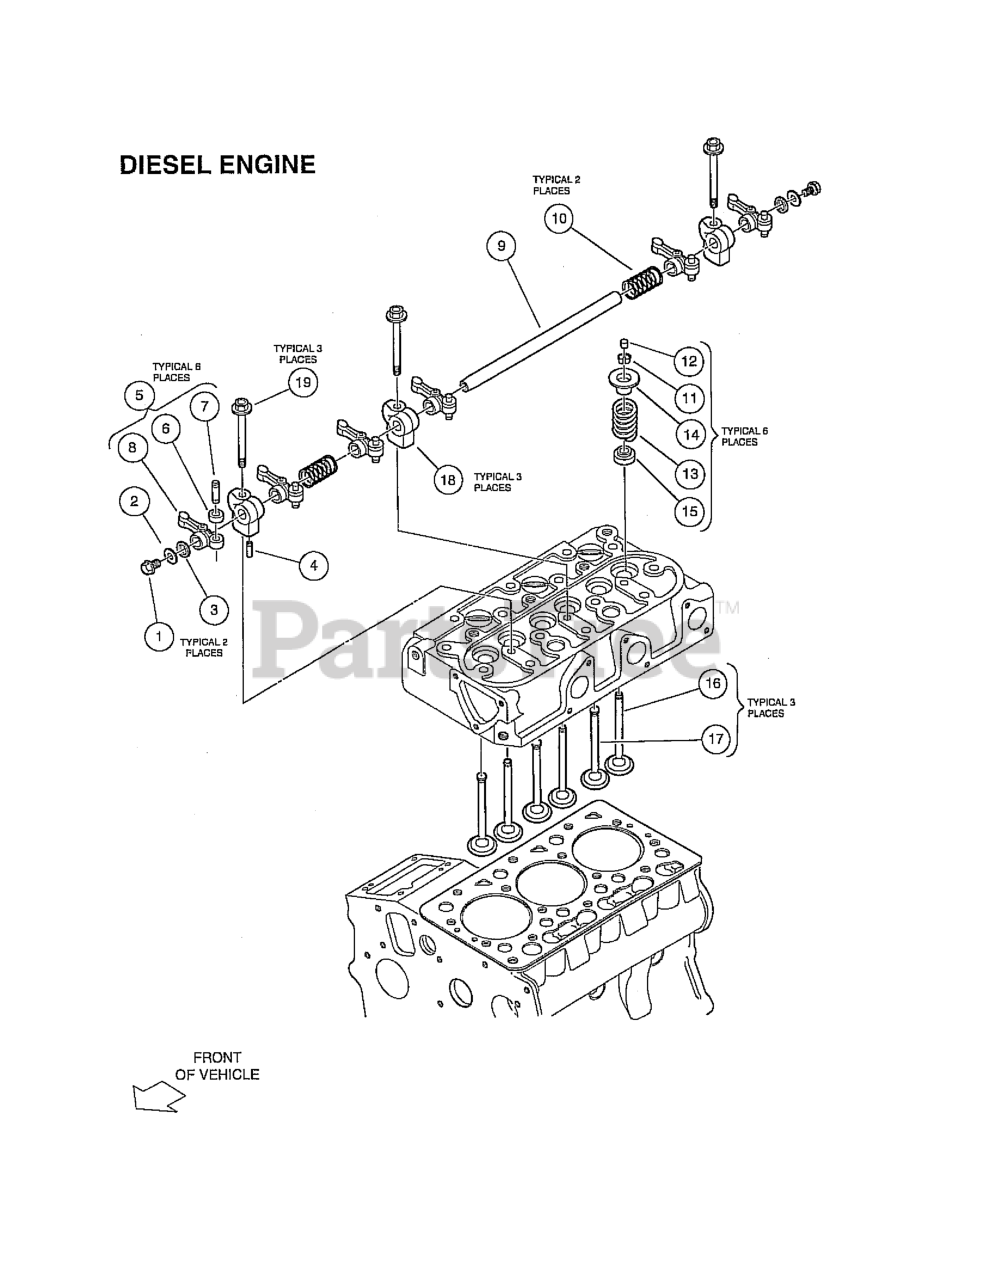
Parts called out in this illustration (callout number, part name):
1	BOLT, M6 X 1 X 8
2	WASHER, D722, PLAIN, ROCKER
3	WASHER, ROCKER ARM
4	PIN, SPRING, D722, ROCKER
5	ASSY ROCKER ARM
7	SCREW-ADJUSTING
9	SHAFT, ROCKER ARM
10	SPRING, ROCKER ARM
11	COLLET, VALVE SPRING, SET
12	CAP, VALVE, D722
13	SPRING, VALVE
14	RETAINER, SPRING
15	SEAL, VALVE STEM
16	VALVE, EXHAUST
17	VALVE, INLET
18	BRACKET-ROCKER ARM
